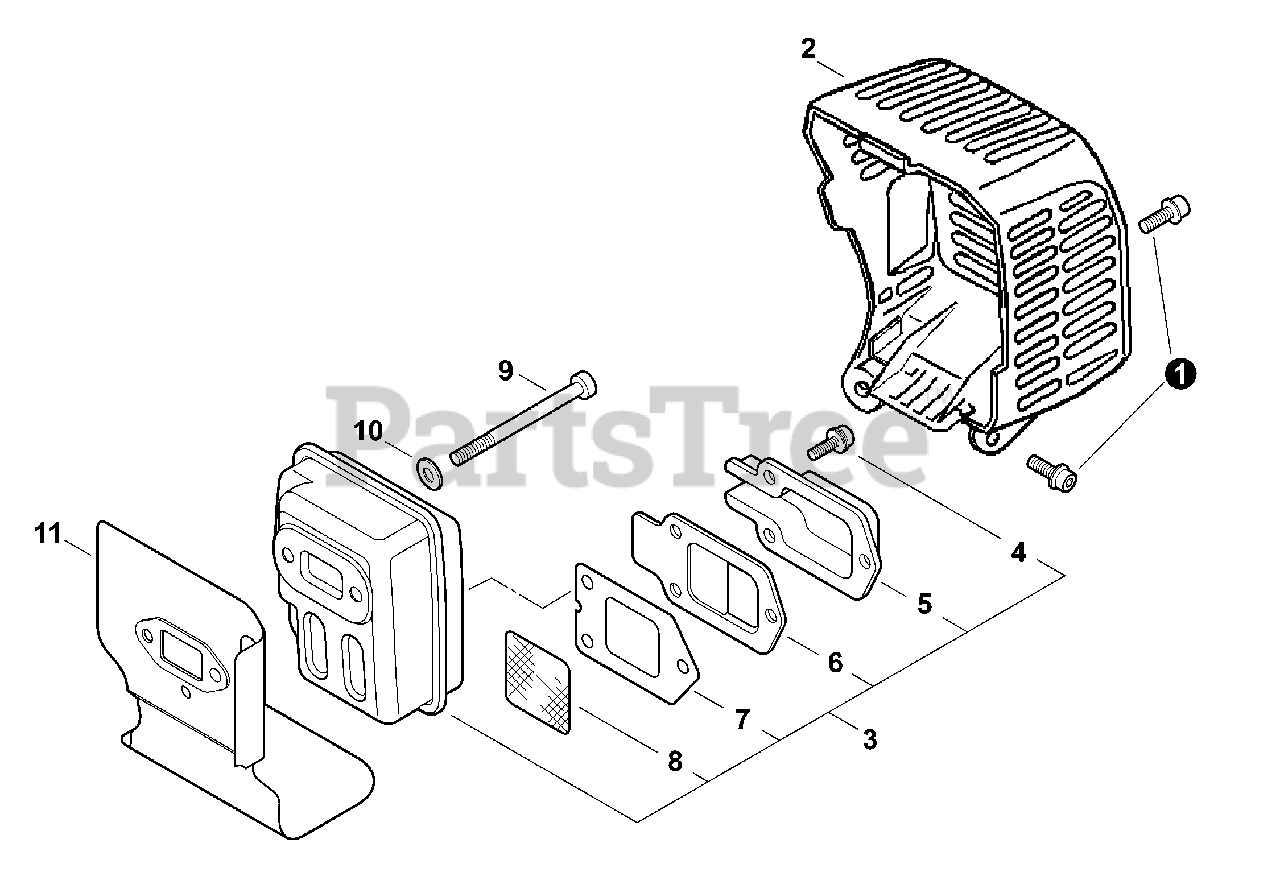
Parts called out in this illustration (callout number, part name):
1	COVER, EXHAUST
2	SCREW - 5×12
3	MUFFLER ASY
4	SCREW - 4×10
5	GUIDE, EXHAUST - OUTER
6	GUIDE, EXHAUST - INNER
7	GASKET, EXHAUST
8	SCREEN, SPARK ARRESTER
9	SCREW - 5×55
10	WASHER - 5
11	SHIELD, EXHAUST
